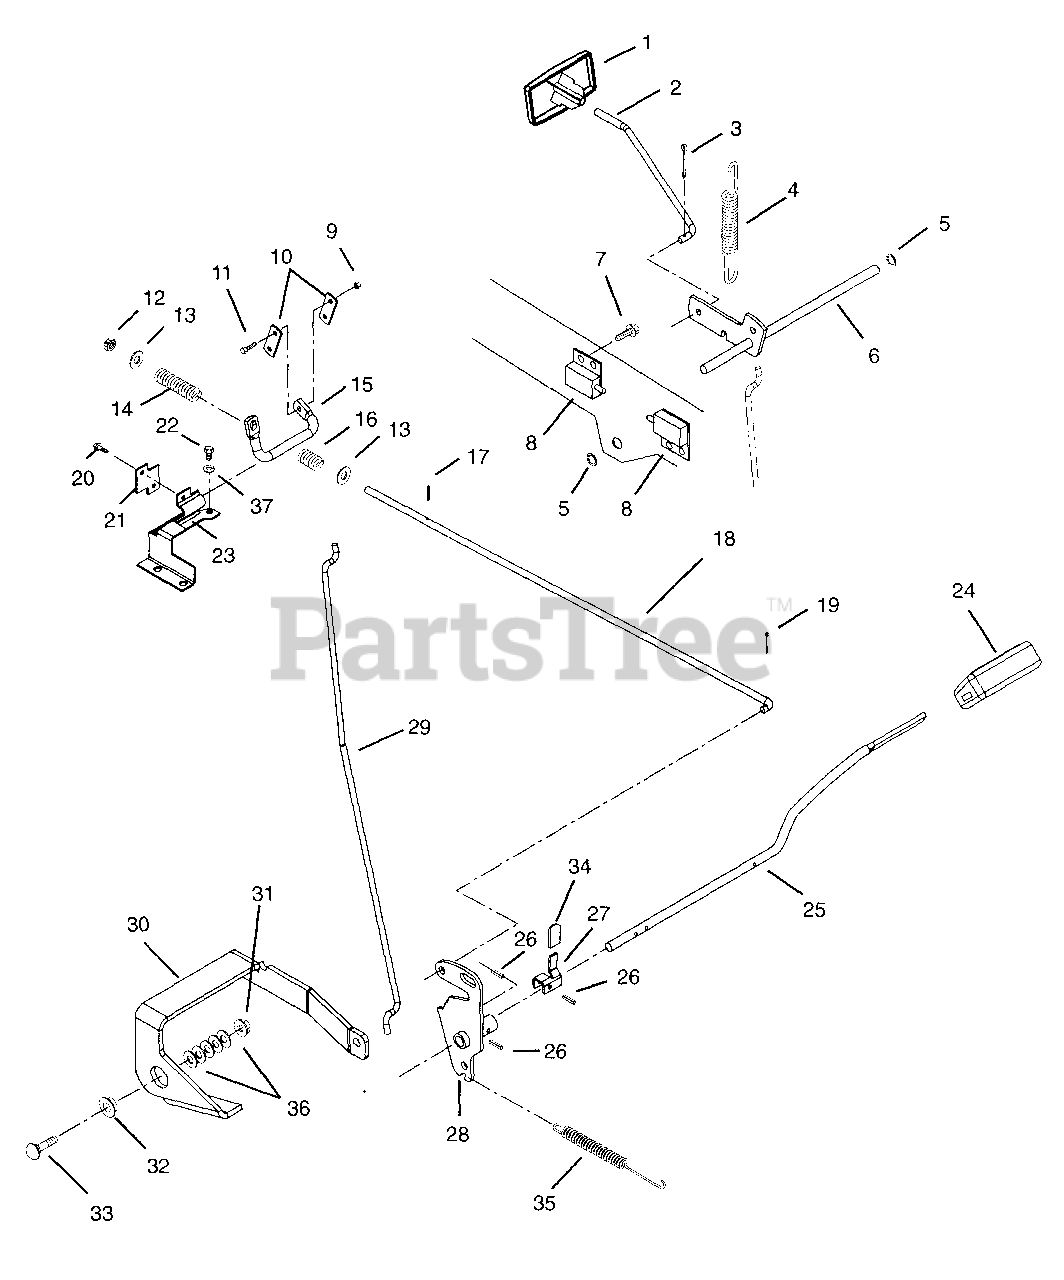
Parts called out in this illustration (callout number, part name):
1	KNOB- PARK BRAKE
2	ROD, PARKING BRAKE
3	PIN-COTR .06X.50
4	SG-TENS .051X.60X2.25 WLD 7.0
5	RG-RTNG-EXT .250X.010
6	BELLCRANK-PARKING BRAKE
7	SCR-TAP 12-24X.50 HWH TR BLACK
8	SWITCH- SINGLE POLE N.O.
9	@NUT-LK-CTR .25-20 YWZC
11	@BLT-HEX .25-20X1.00 GR5 YWZC
12	@NUT-LK-CTR .38-16 YWZC
13	@WSHR-FL-STL.406X.812X.065 YWZ
14	SG-COMP 2.00X.404
15	ROD, BRAKE PIVOT
16	SG-COMP .62X.68X1.75
17	PIN-ROLL .125X.75
18	ROD, BRAKE
19	@PIN-CTR .09X.75 EXTPRSQCT YWZ
20	@SCR-TAP .25-20X.37 HWH YWZ TR
21	PLATE, HOLDING
22	@BLT-HEX .31-18X.50 GR5 YWZC
23	BRACKET, BRAKE ROD PIVOT
24	COVER - PEDAL - BRAKE
25	PEDAL - BRAKE
26	PIN-GRV .188X1.25 TP A
27	LEVER - BRAKE SWITCH
28	ARM + HUB - BRAKE
29	ROD, PARKING BRAKE
30	LEVER, PARKING BRAKE
31	@NUT-SPNLK-FLG .312-18 YWZC
32	BSHG, FLG .325X.499X.26X.88
33	BLT-RDHDSQNK .31-18X1.0 SHTYZ
34	GRIP .062 X .375 X 1.000 RE
35	SG-TENS .105X.85X5.00 WLD 40
36	WSHR-PLASTIC .390X.875X.062
37	WSHR-LK .312X.097 HVY YWZC
